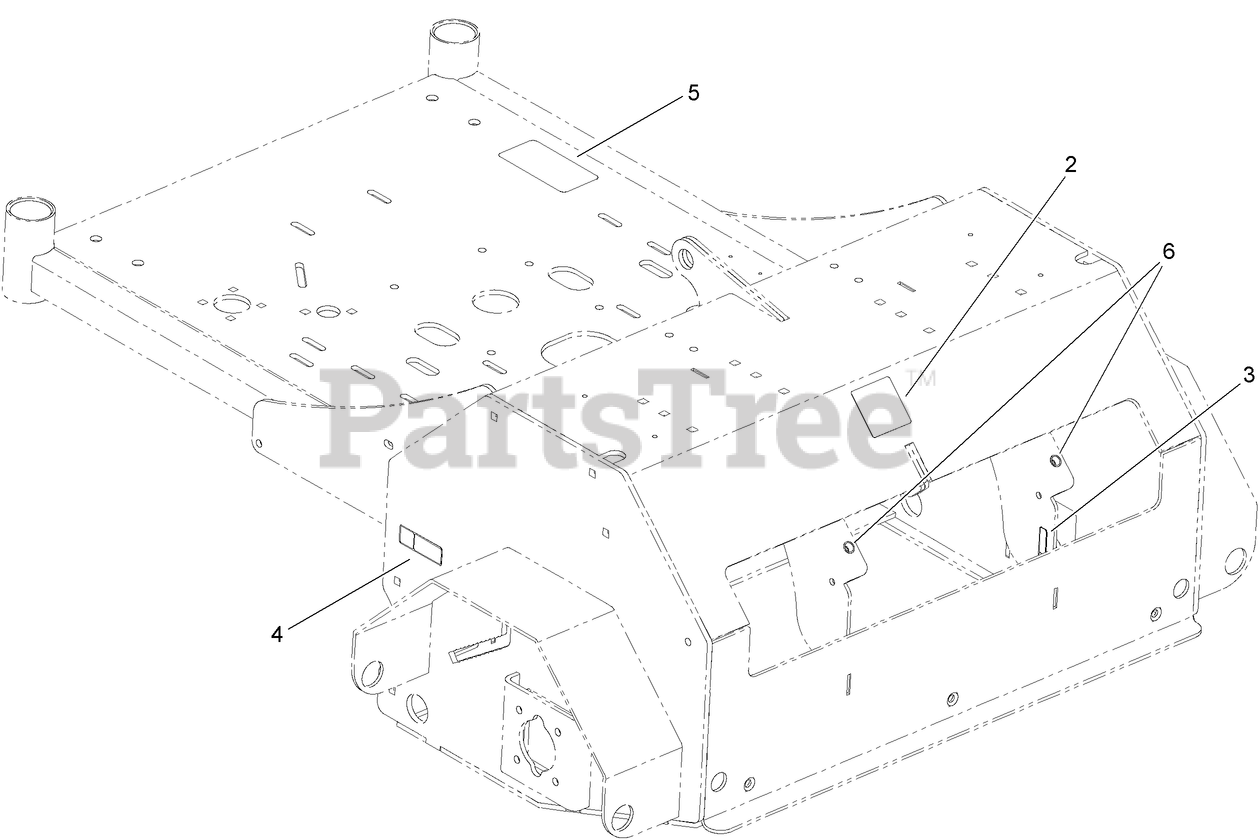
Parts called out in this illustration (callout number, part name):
2	DECAL-WARNING
3	DECAL-WARNING
4	DECAL-DANGER
5	DECAL-BELT ROUTING
6	INSERT-NUT
